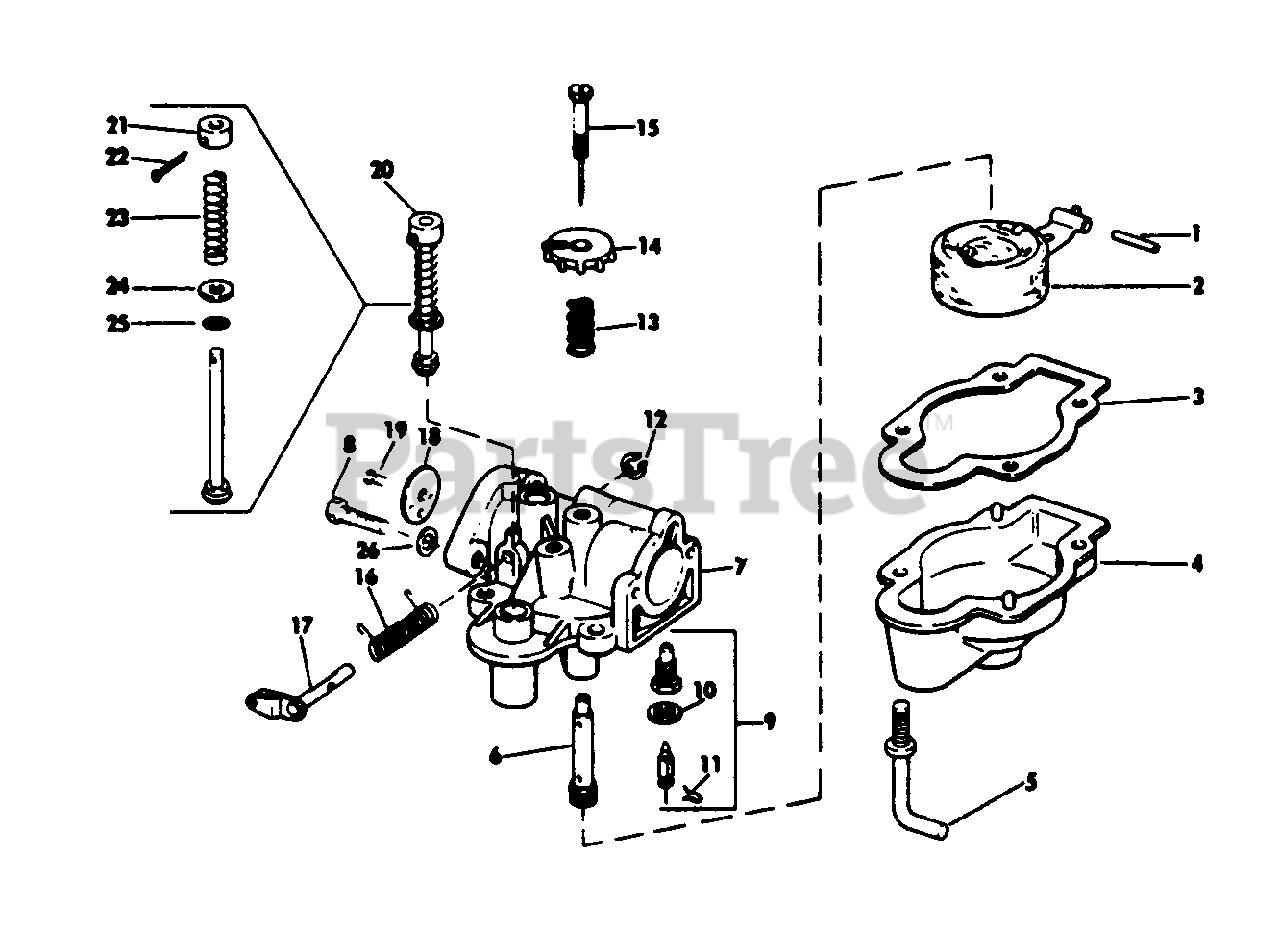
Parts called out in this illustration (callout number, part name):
1	Pin-Float Arm Hinge
2	Float and Arm Assy.
3	Gasket-Float Chamber
4	Chamber-Float
5	Screw-Float Chamber
7	Carburetor Body Assy.
9	Float Valve and Seat
10	Washer-Float Valve Seat
11	Clip
12	Grip Ring
13	Spring-Needle Adj.
14	Knob-Needle Adj.
15	Needle Assy.
16	Spring-Throttle
17	Throttle Shaft and Lever Assy.
18	Disc-Throttle
19	Scr.-Throttle Shaft Disc.
20	Primer Assembly
21	Knob Primer
22	Cotter Pin
23	Spring Compression
24	Washer-Plain
25	"O" Ring
